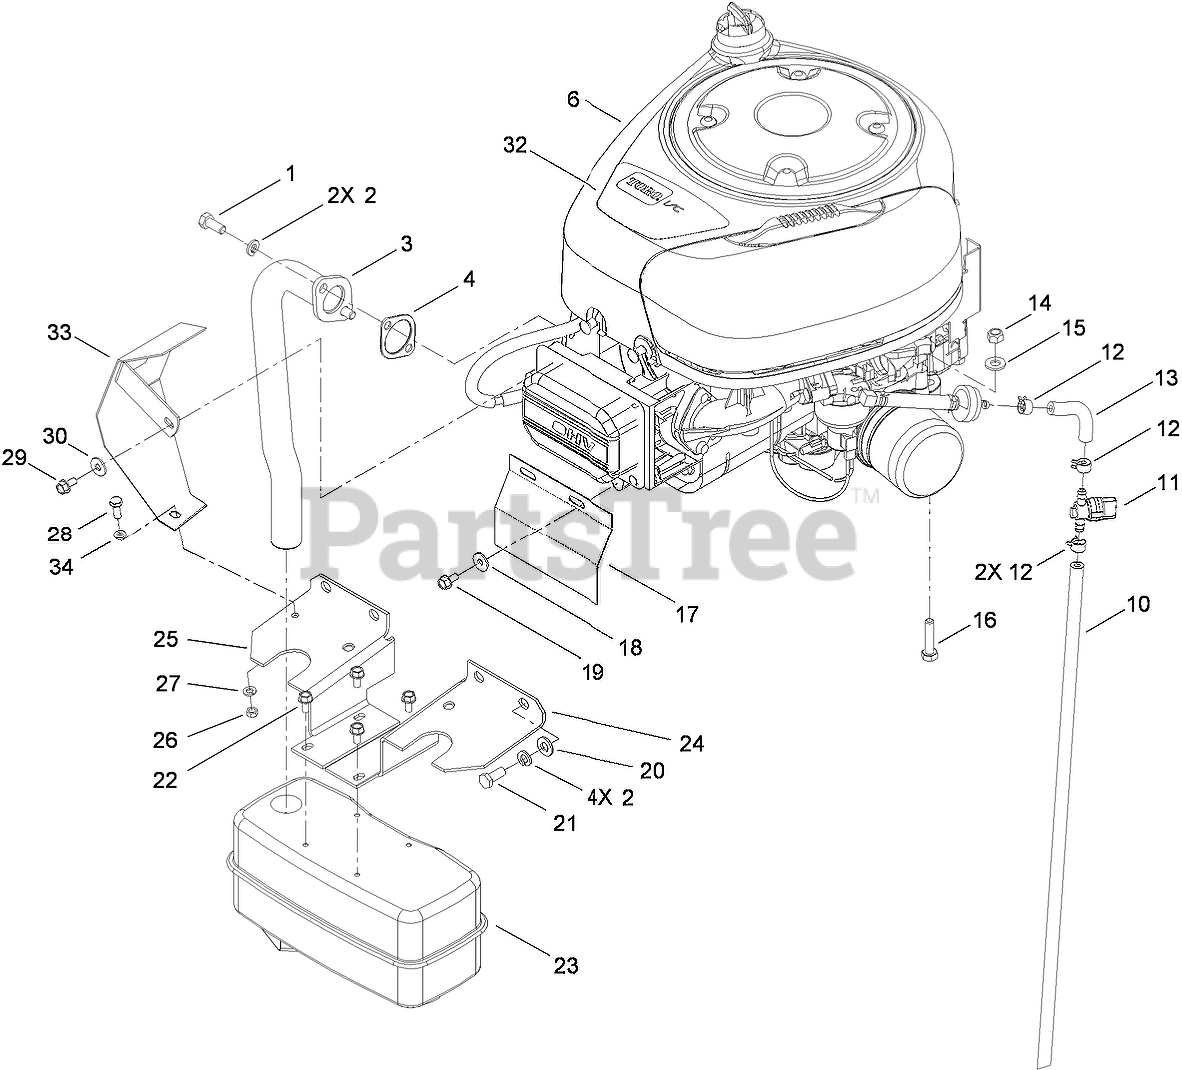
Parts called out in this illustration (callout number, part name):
1	SCREW-HH
2	WASHER-LOCK, SPRING
3	TUBE-EXHAUST
4	GASKET-EXHAUST
10	LINE-FUEL
11	VALVE-TANK, FUEL
12	CLAMP-LINE, FUEL
13	LINE-FUEL
14	NUT-LOCK, NI
15	WASHER-PLAIN
16	SCREW-HH
17	COVER-FRONT
18	WASHER-FLAT
20	WASHER-PLAIN
21	SCREW-HH
23	MUFFLER
24	GUARD-MUFFLER, LH
25	GUARD-MUFFLER, RH
26	NUT-HEX
27	WASHER-SPRING
28	SCREW-HH
30	WASHER-FLAT
32	DECAL-ENGINE
33	Cover-Manifold, Exhaust
34	WASHER-FLAT
